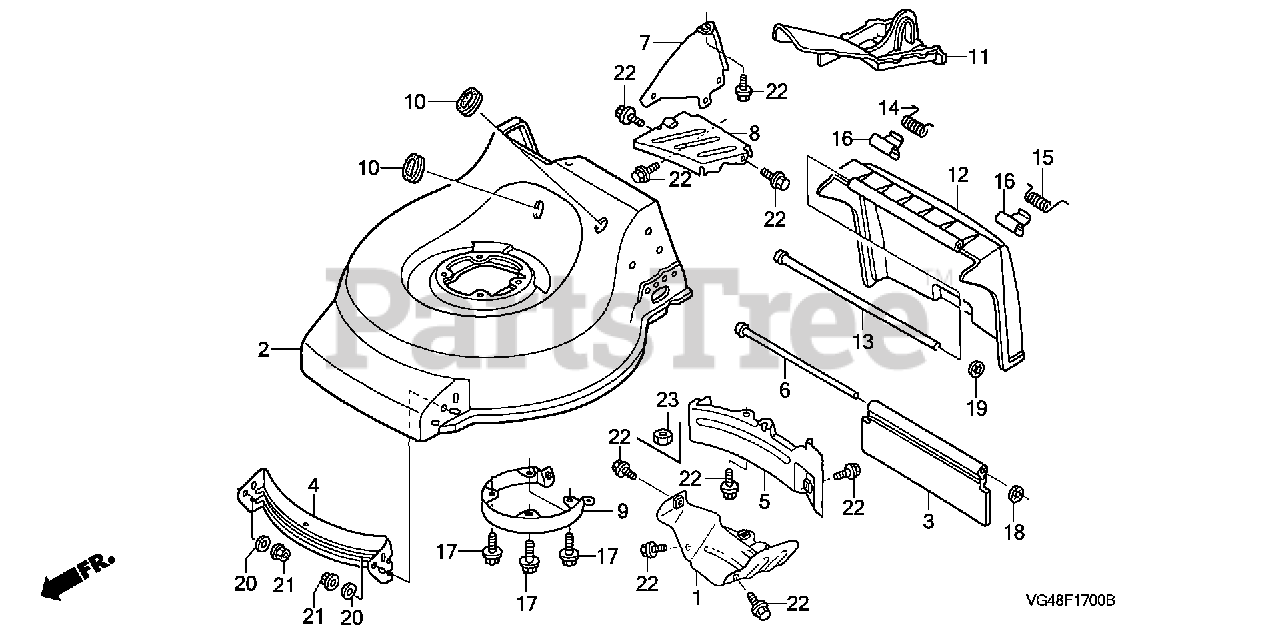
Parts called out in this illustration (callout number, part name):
1	COVER, BELT
2	HOUSING, CUTTER *NH190M* (VINTAGE GRAY METALLIC)
2	HOUSING, CUTTER *NH192M* (GENTLY SILVER METALLIC)
3	SHIELD, RR.
4	SCROLL, FR.
5	SCROLL, RR.
6	SHAFT, RR. SHIELD (405MM)
7	PLATE, SCROLL
8	PLATE, GUIDE
9	COVER, ROTO-STOP
10	GROMMET, CABLE (HOLE)
11	STUFFING *NH105* (MAT BLACK)
11	STUFFING *NH1* (BLACK)
12	GUARD, DISCHARGE *NH105* (MAT BLACK)
13	SHAFT, DISCHARGE GUARD
14	SPRING, R. GUARD RETURN
15	SPRING, L. GUARD RETURN
16	PLATE, HINGE
17	BOLT, FLANGE (5/16-24X1")
18	NUT, PUSH (3.96MM) (CAPPED TYPE)
18	NUT, PUSH (3.96MM) (FLAT ROUND TYPE)
19	NUT, PUSH (7.94MM)
20	WASHER, PLAIN (5/16)
21	NUT, FLANGE (8MM)
22	BOLT, FLANGE (6X10)
23	NUT, NYLON LOCK (6MM)
